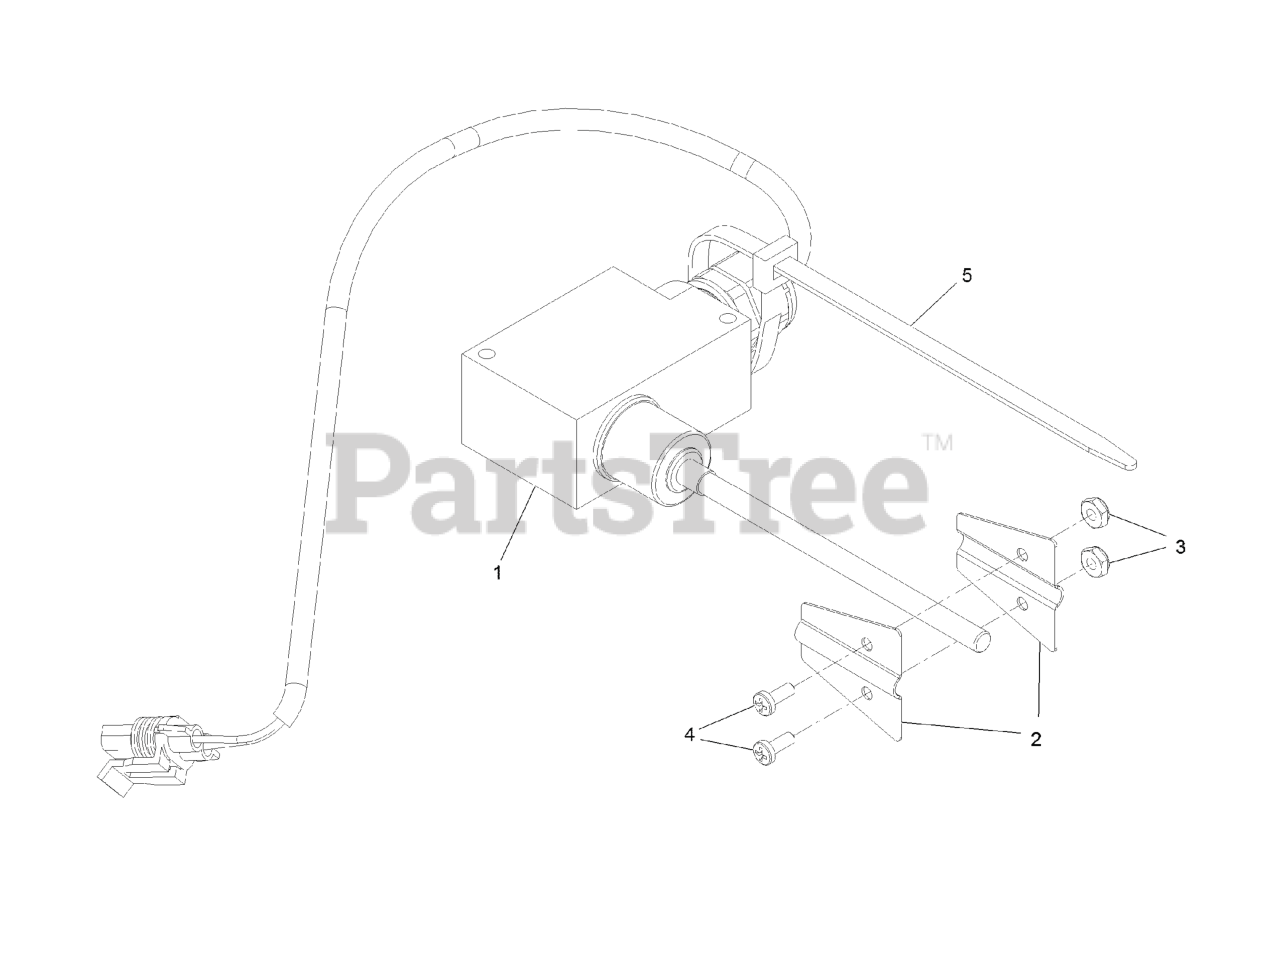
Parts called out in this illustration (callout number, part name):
1	FILL SENSOR WIRE KIT
2	FLAG- SENSOR, FILL
3	NUT-HEX
4	SCREW-PAN
5	TIE-PLASTIC
